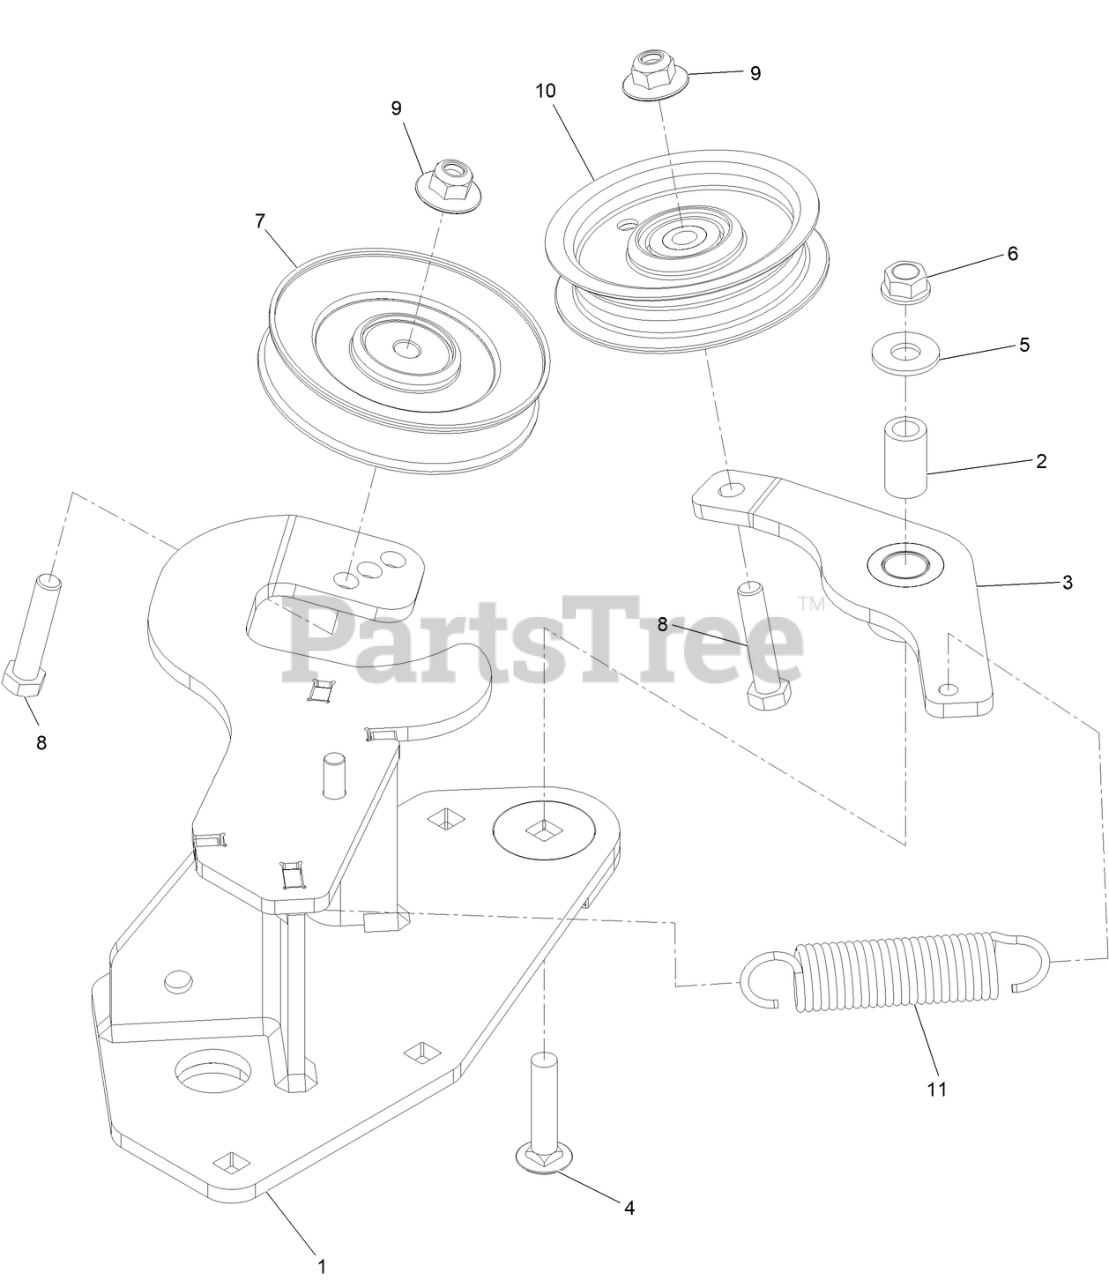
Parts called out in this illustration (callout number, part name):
1	Idler ASM-Blower [black]
2	BUSHING-PIVOT, IDLER
3	IDLER ASM
4	SCREW-CARR
5	WASHER-FLAT
6	NUT-HHF, WHIZ
7	PULLEY-IDLER
8	SCREW-HH
9	Nut-Nyloc 3/8-16 Flg
10	PULLEY-IDLER, FLAT
11	SPRING-EXTENSION
